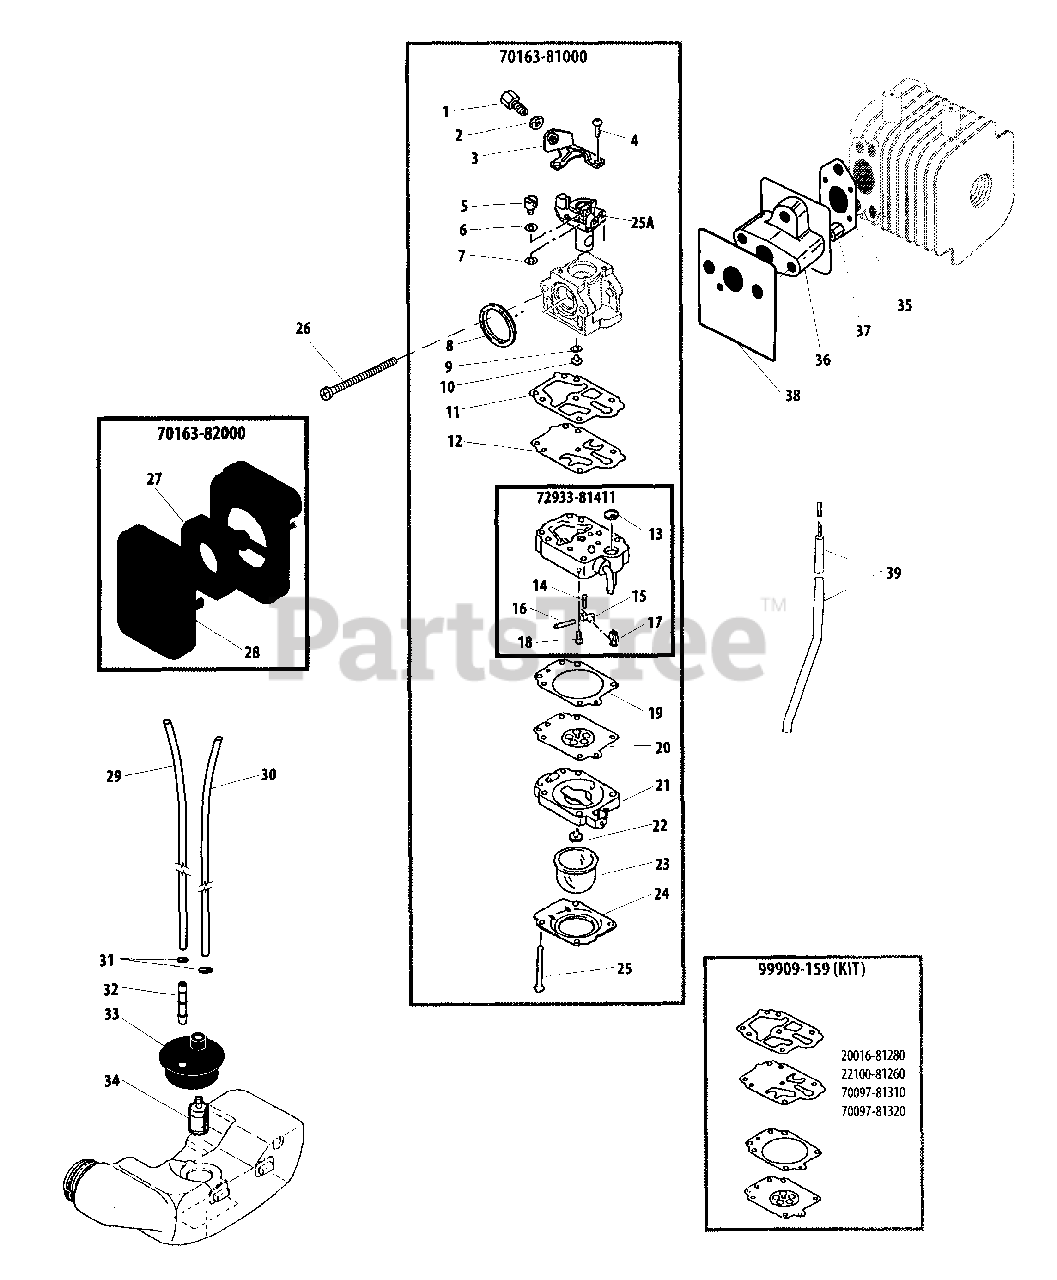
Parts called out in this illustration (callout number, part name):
1	NUT, CABLE ADJUST
2	NUT
3	BRACKET, CABLE
4	SCREW
5	SWIVEL
6	WASHER
7	RING, RETAINING
8	SEAL
9	O-RING
10	JET, MAIN - 37
11	GASKET, PUMP
12	DIAPHRAGM, PUMP
13	STRAINER
14	SPRING, METERING LEVER
15	LEVER, METERING
16	PIN, METERING LEVER
17	VALVE, INLET NEEDLE
18	SCREW, METERING LEVER PIN
19	GASKET, METERING
20	DIAPHRAGM, METERING
21	BASE, PURGE
22	VALVE, CHECK
23	BULB, PURGE
24	RETAINER, PURGE BULB
25	SCREW, PUMP COVER
25A	THROTTLE VALVE ASSY
26	SCREW - 5X70
27	FILTER, AIR
28	COVER, AIR FILTER
29	PIPE - RETURN
30	PIPE - FUEL
31	RING, RETAINING - 6
32	CONNECTOR, PIPE
33	GROMMET
34	FILTER, FUEL
36	INSULATOR
37	NUT
38	GASKET
39	CABLE, THROTTLE
70163-81000	CARBURETOR
70163-82000	AIR FILTER CASE ASSY
72933-81411	BASE, PURGE
99909-159	DIAPHRAGM/GASKET KIT
